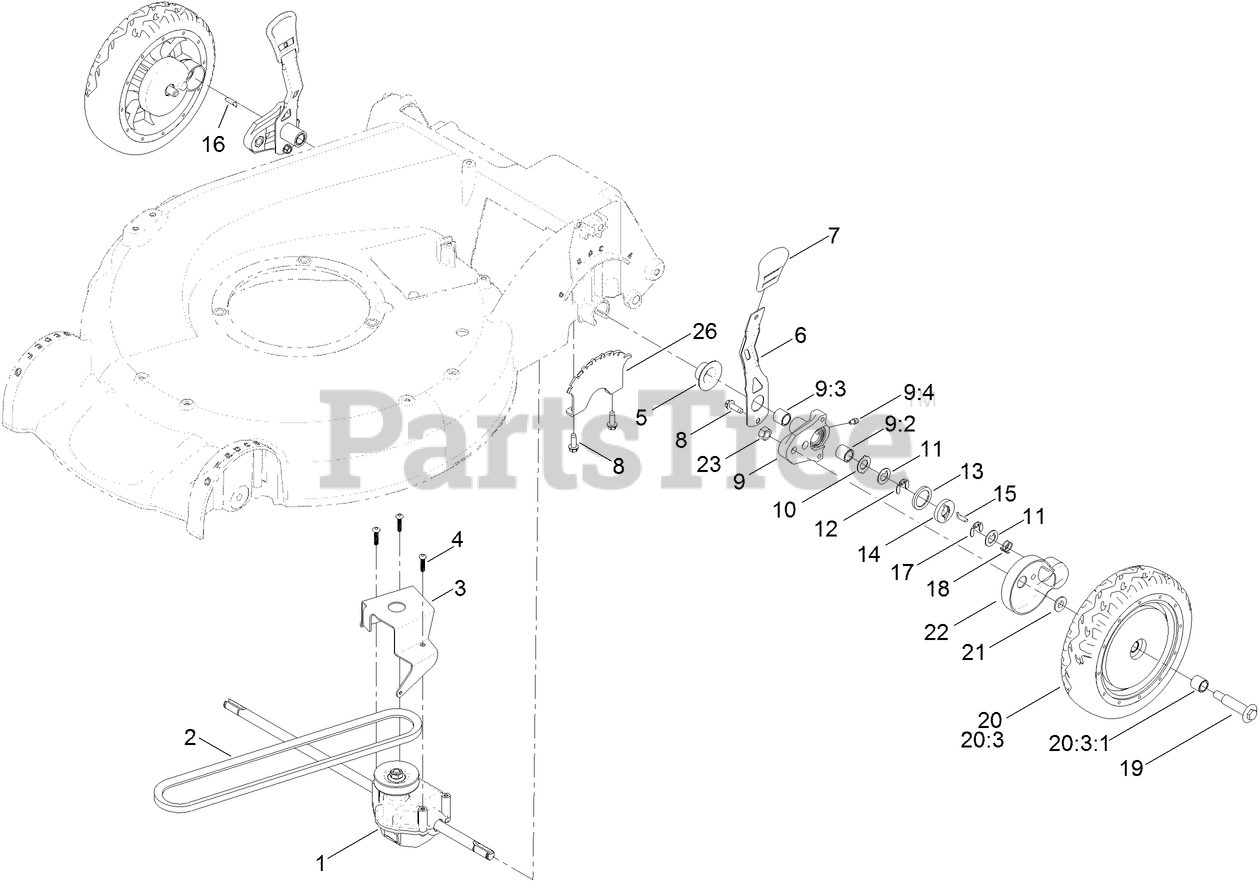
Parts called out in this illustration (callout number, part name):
1	TRANSMISSION ASM
2	V-BELT
3	BRACKET-TRANSMISSION
4	SCREW-PLASTITE
5	CAP-END
6	ARM-SPRING
7	KNOB-HOC
8	SCREW-HWHTF
9	PIVOT ARM ASM
9:2	BUSHING
9:3	BUSHING
9:4	FITTING-GREASE
10	WASHER-ARM, PIVOT
11	WASHER-THRUST, KEYED
12	RING-RETAINING,CLIP
13	RING-FRICTION
14	WASHER-CLUTCH
15	KEY-ROCKING, LH
16	KEY-ROCKING, RH
17	GEAR-PINION
18	SPRING-COMPRESSION
19	BOLT-SHOULDER
20	WHEEL GEAR ASM
20:3	WHEEL ASM
20:3:1	BUSHING
21	SPACER-COVER, WHEEL
22	COVER-WHEEL
23	NUT-HEX
26	PLATE-HOC
